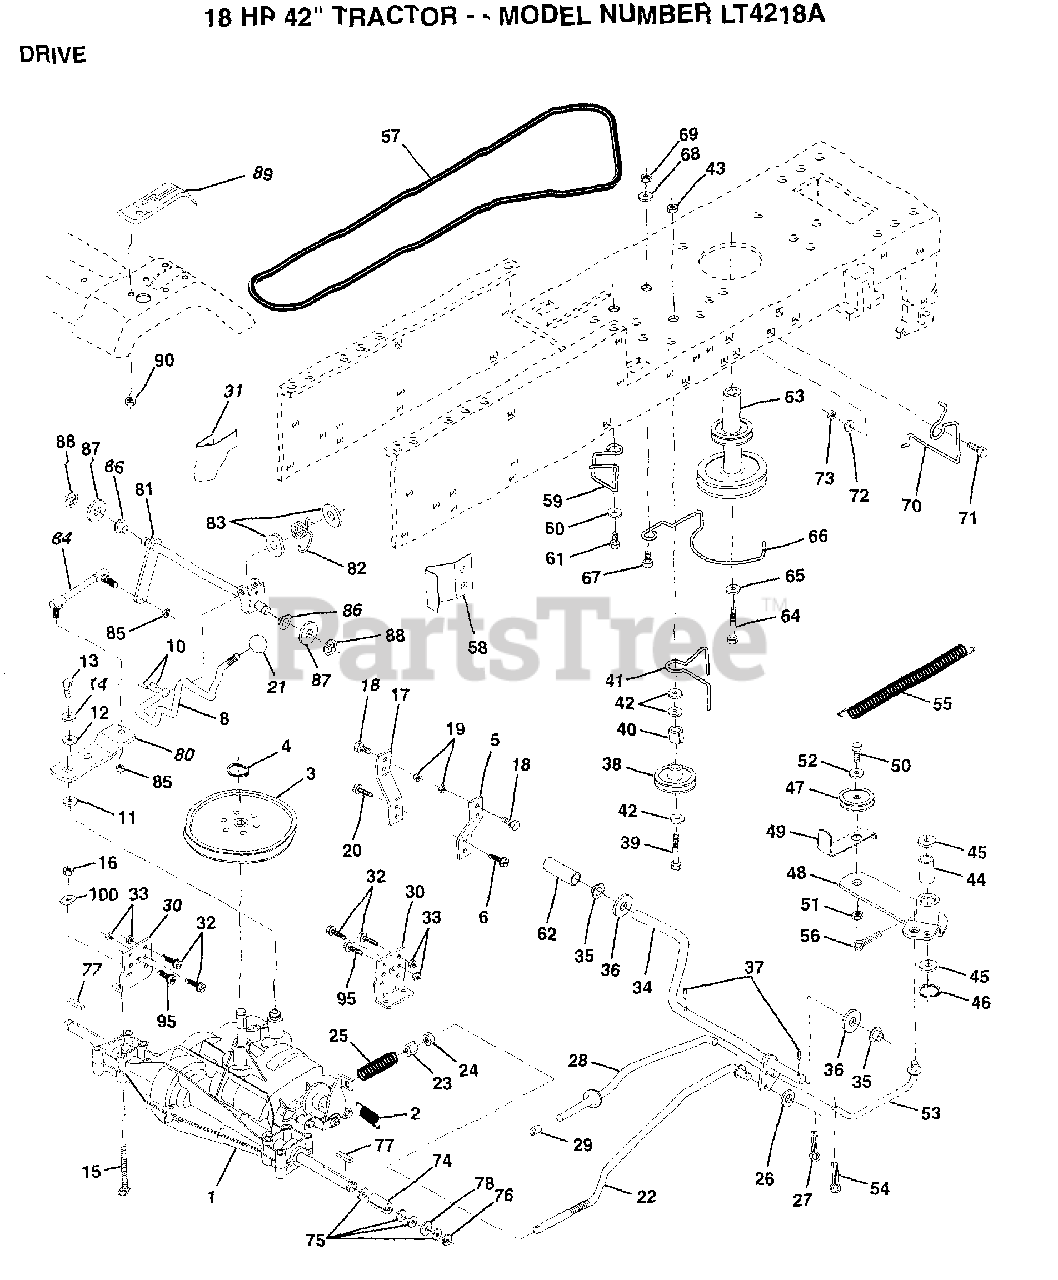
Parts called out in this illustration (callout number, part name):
3	"PULLEY,TRANSAXLE"
5	STRAP TORQUE
6	SCREW
8	ROD SHIFT FEND LT
10	PIN COTTER 1/8
11	WASH-SHFT PLT LT
12	WASHER
14	LOCKWASHER
15	BOLT HEX
16	NUT
17	STRAP TORQUE
18	BOLT
19	NUT
20	SCREW
21	KNOB T (1/2-HOLE)
22	BRAKE ROD
23	NUT
24	NUT
25	SPRING ROD LT
26	WASHER
27	COTTER PIN
28	BRAKE PARK ROD
29	PLUNGER CAP T
30	TRANSAXLE MTG BKT
31	"KEEPER,BELT LH T"
32	BOLT
33	NUT
35	NYLON BEARING
36	WASHER LT
38	PULLEY.IDLER.FLAT
39	BOLT
40	SPACER T
41	BELT KEEPER LT
42	WASHER
43	NUT
44	"LY, BEARING"
45	WASHER LT
46	KLIP RING
48	ARM IDLER
49	RETAIN BELT
52	WASHER
53	"LINK, CLUTCH T"
54	COTTER PIN
55	"SPRING, RETURN LT"
56	COTTER PIN
58	"KEEPER,BELT RH T"
59	KEEPER BELT CNTSP
60	WASHER
61	SCREW
62	PEDAL COVER T
63	PULLEY.ENGINE
64	BOLT
65	LOCKWASHER
66	KEEPER.BELT.ENG.L
67	BOLT
68	WASHER
70	KEEPER BELT ENG
71	BOLT
72	WASHER
74	SPACER LT
75	WASHER
76	E-RING LT
77	SQUARE KEY
78	WASHER
80	ARM SHIFT TRANS
81	SHAFT ASM.SHIFT
82	"SPRING,TORSION"
83	WASHER
84	TIE ROD
85	NUT 1/4-28
86	BUSHING
87	WASHER D
88	KLIP RING
90	NUT
95	SCREW
100	WASHER M
